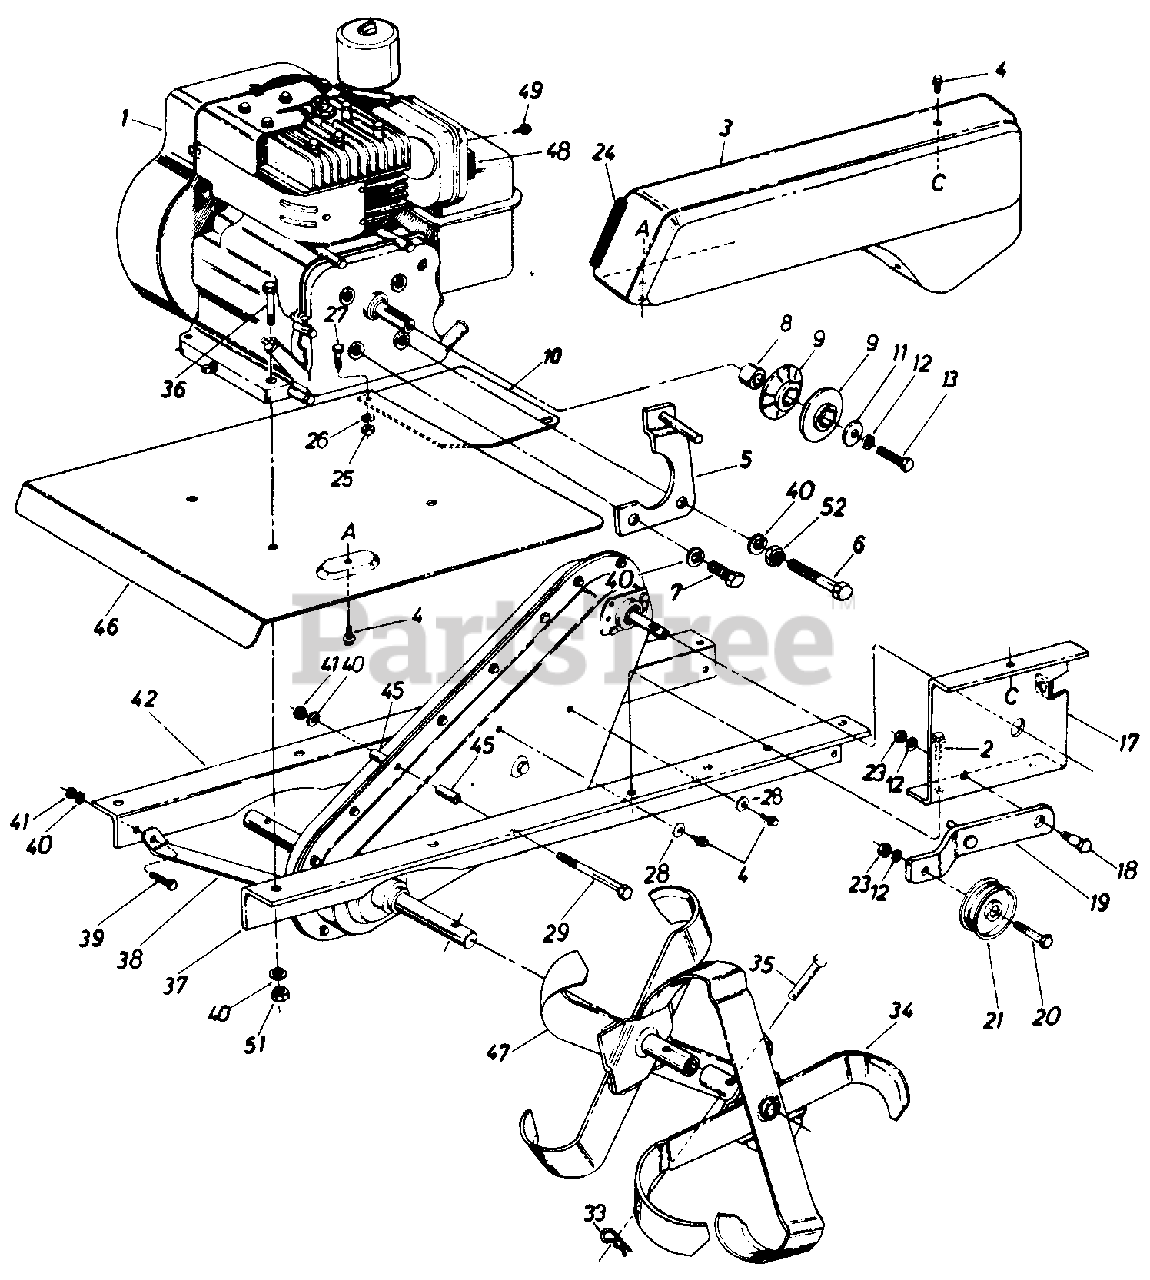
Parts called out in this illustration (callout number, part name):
1	Engine
2	Hex Self-Tap Scr. 5/16-24 x .5"
3	Belt Cover
4	Hex Self-Tap Scr. 1/4-20 x .5"
5	Belt Keeper Brkt. Ass'y.
6	Hex Bolt 5/16-24 x 2.25" Lg.(Gr. 5)
7	Hex Bolt 5/16-24 x .62" Lg. (Gr. 5)
8	Spacer
9	Pulley Half
10	Tine Shield Extension
11	Fl-Wash. 3/8" I.D. x 1.25"
12	L-Wash. 3/8" I.D.
13	Hex Bolt 3/8-24 x 1.00" Lg.
17	Idler Mounting Brkt.
18	Shld. Bolt
19	Idler Bracket Ass'y.
20	Hex Bolt 3/8-16 x 1.5" Lg.
21	Idler Pulley
23	Hex Jam Nut 3/8-16 Thd.
24	Trim Strip-3"
25	Hex Nut 1/4-20 Thd.
26	L-Wash. 1/4" I.D.
27	Hex Bolt 1/4-20 x .62 Lg.
28	Bell-Wash. .26 I.D. x .75 O.D.
29	Hex Bolt 5/16-18 x 3" Lg.
33	Hairpin Cotter
34	See Tine Chart
35	Clevis Pin
36	Hex Bolt 5/16-18 x 1.5" Lg.
37	Frame Rail-L.H.
38	Front Brace Brkt.
39	Hex Bolt 5/16-18 x .75" Lg.
40	L-Wash. 5/16" I.D.
41	Hex Cent. L-Nut 5/16-18 Thd.
42	Frame Rail-R.H.
45	Spacer
46	Tine Shield
47	See Tine Chart
48	Deflector
49	Hex Self-Tap Scr. #8-32 x.38" Lg.
51	Hex Nut 5/16-18 Thd.
52	Hex Nut 5/16-24 Thd.
